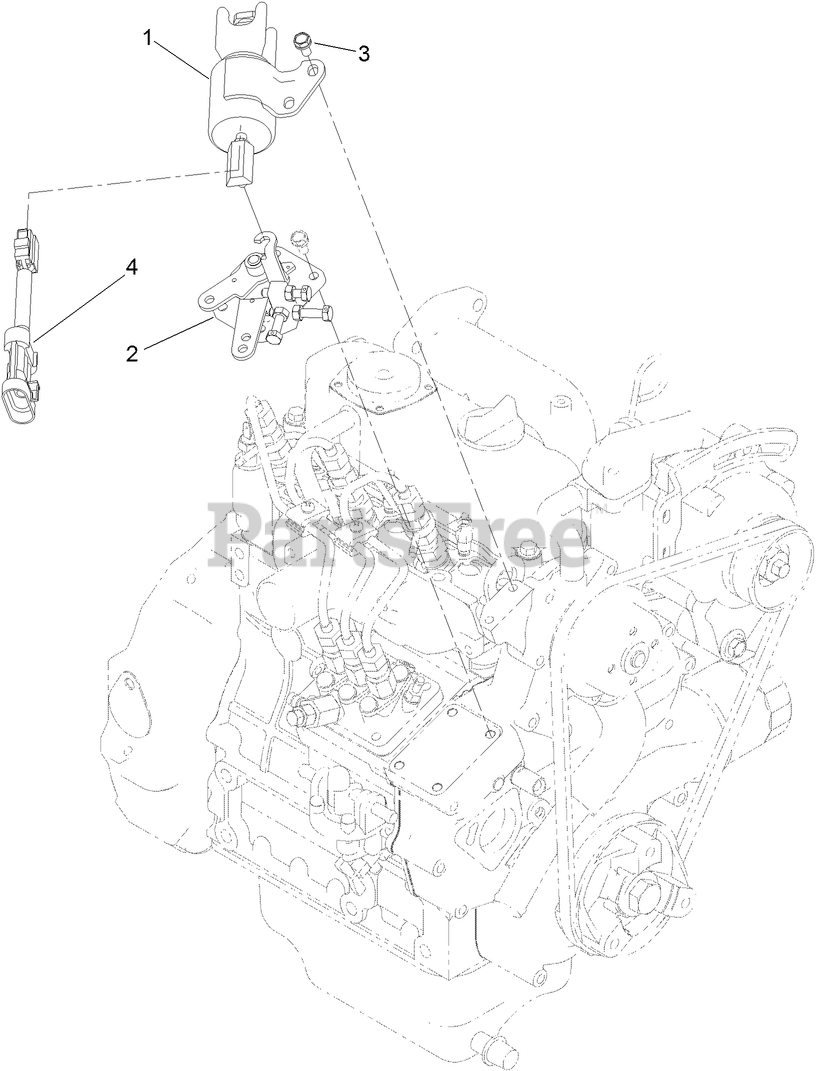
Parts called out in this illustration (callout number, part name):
1	SOLENOID-SHUT OFF/ON
2	PLATE-CONTROL, SPEED
3	BOLT-FLANGE
4	HARNESS-STUB
